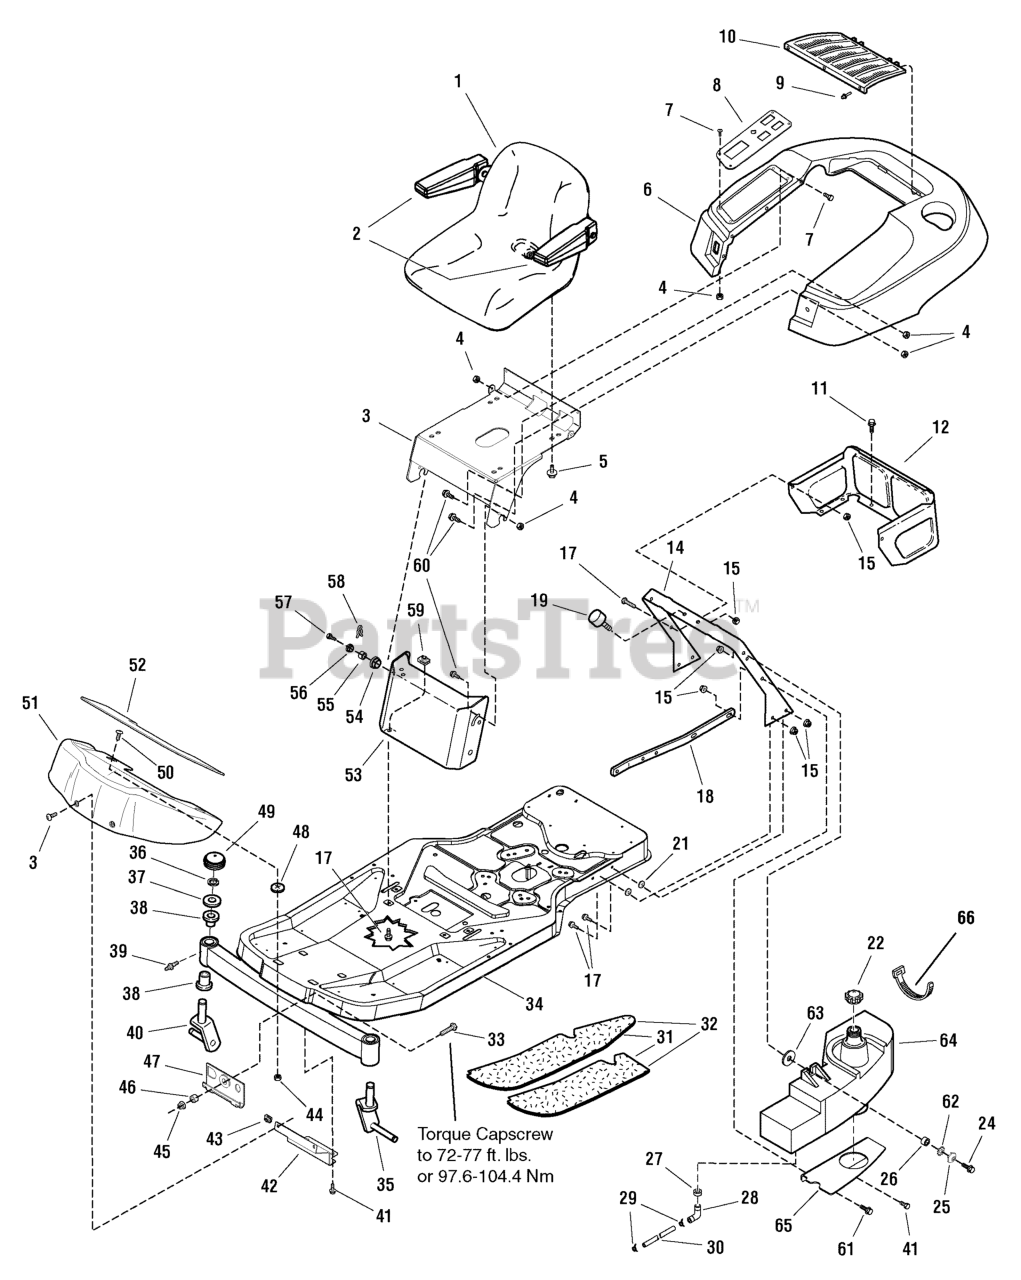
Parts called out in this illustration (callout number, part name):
1	SEAT ASSEMBLY, with Arm Rests
2	ARM REST KIT, (L.H. & R.H.)
3	SUPPORT, Seat
4	NUT, Hex Flange ESNA, 1/4-20
5	CAPSCREW, Hex Head Whiz Lock Dog Point, 5/16-18 x 3/4
6	DECK, Seat
7	SCREW, Truss Head Torx Drive, 1/4-20 x 3/4
8	PLATE, Pod Control
9	RIVET, Pop
10	SCREEN, Seat Deck
11	CAPSCREW, Hex Washer Head Taptite, 1/4-20 x 1/2
12	SHROUD, Rear
14	SUPPORT, Seat Deck
15	NUT, Hex Flange Whiz Lock, 5/16-18
17	CAPSCREW, Hex Head Whix Lock, 5/16-18 x 3/4, G5
18	BRACE, Tank
19	BUMPER, Rubber
21	NUT, Push
22	CAP, Fuel Tank
24	CAPSCREW, Hex Washer Head Taptite, 5/16-18 x 1-1/2
25	WASHER, 5/16
27	BUSHING, Fuel Tank
28	ELBOW, with Screen, Gas Tank to Fuel Line
29	CLAMP, Hose, Wire Type E
30	HOSE, Fuel 8.5" Long
31	PAD, Footrest, R.H.
32	PAD, Footrest, L.H.
33	CAPSCREW, Hex, 1/2-13 x 1-1/2
34	FRAME & SPINDLES ASSEMBLY
35	ARM, Caster, L.H.
36	RING, E-Retaining
37	WASHER
39	FITTING, Lube
40	ARM, Caster, R.H.
41	SCREW, Hex Washer Head Taptite, 5/16-18 x 3/4
42	BRACKET, Footrest Support
43	NUT, Speed Lug Type, 1/4-20
44	NUT, Hex Flange Whiz Lock, 1/4-20
45	NUT, Hex Flange, Two-Way Lock, 1/2-13
47	HOOK & WASHER ASSEMBLY
48	NUT, Push, 1/4
49	CAP, Hub
50	CARRIAGE BOLT, 1/4-20 x 3/4
51	PANEL, Footrest
52	PAD, Footrest, Front
53	PANEL, Front
56	PIVOT, Hood
57	PIN, Quick
58	CAPSCREW, Hex Washer Head Taptite, 5/16-18 x 1
59	NUT, Speed, Lug Type, 5/16-18
60	SCREW, Hex Flange Whiz Lock, 1/4-20 x 5/8
61	CAPSCREW, Hex Flange Whiz Lock, 5/16-18 x 1-1/4, G5
62	LOCKWASHER, External Tooth, 3/8
63	WASHER, 3/8 x 1-1/4 x 1/4
64	TANK, Fuel
65	BRACKET, Fuel Tank
66	TIE, Self-Locking
